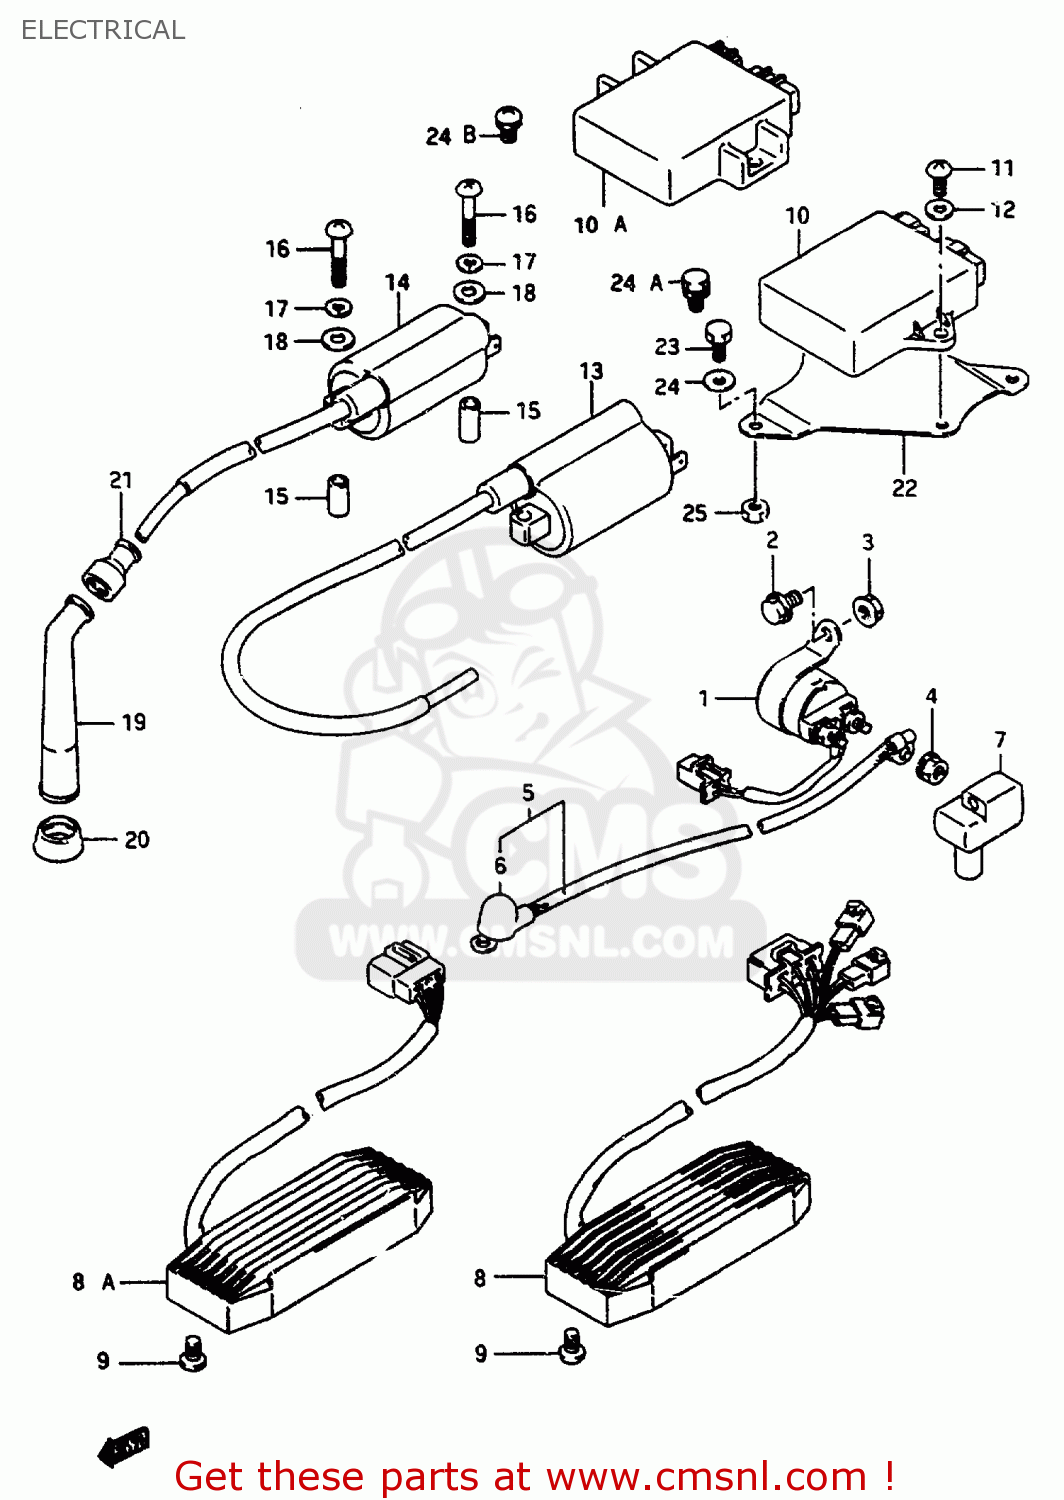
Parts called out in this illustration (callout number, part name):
1	RELAY ASSY,STARTING MOTOR
2	BOLT
3	NUT
4	NUT
5	WIRE,STARTER MOTOR LEAD
6	CAP,STARTER MOTOR LEAD
7	CAP,STARTER RELAY
8	RECTIFIER ASSY
8A	RECTIFIER ASSY
9	BOLT
10	IGNITER UNIT ASSEMBLY
10A	IGNITOR ASSY
11	SCREW
12	WASHER
13	COIL ASSY,IGNITION
14	COIL ASSY,IGNITION
15	SPACER(6.4X10X19)
16	SCREW (5X38)
17	LOCK,WASHER
18	WASHER
19	CAP,SPARK PLUG
20	SEAL,SPARK PLUG CAP
21	SEAL,HIGH TENSION CORD
22	PLATE,IGNITOR FITING
23	BOLT
24	LOCK WASHER
24A	BOLT
24B	BOLT
25	NUT
